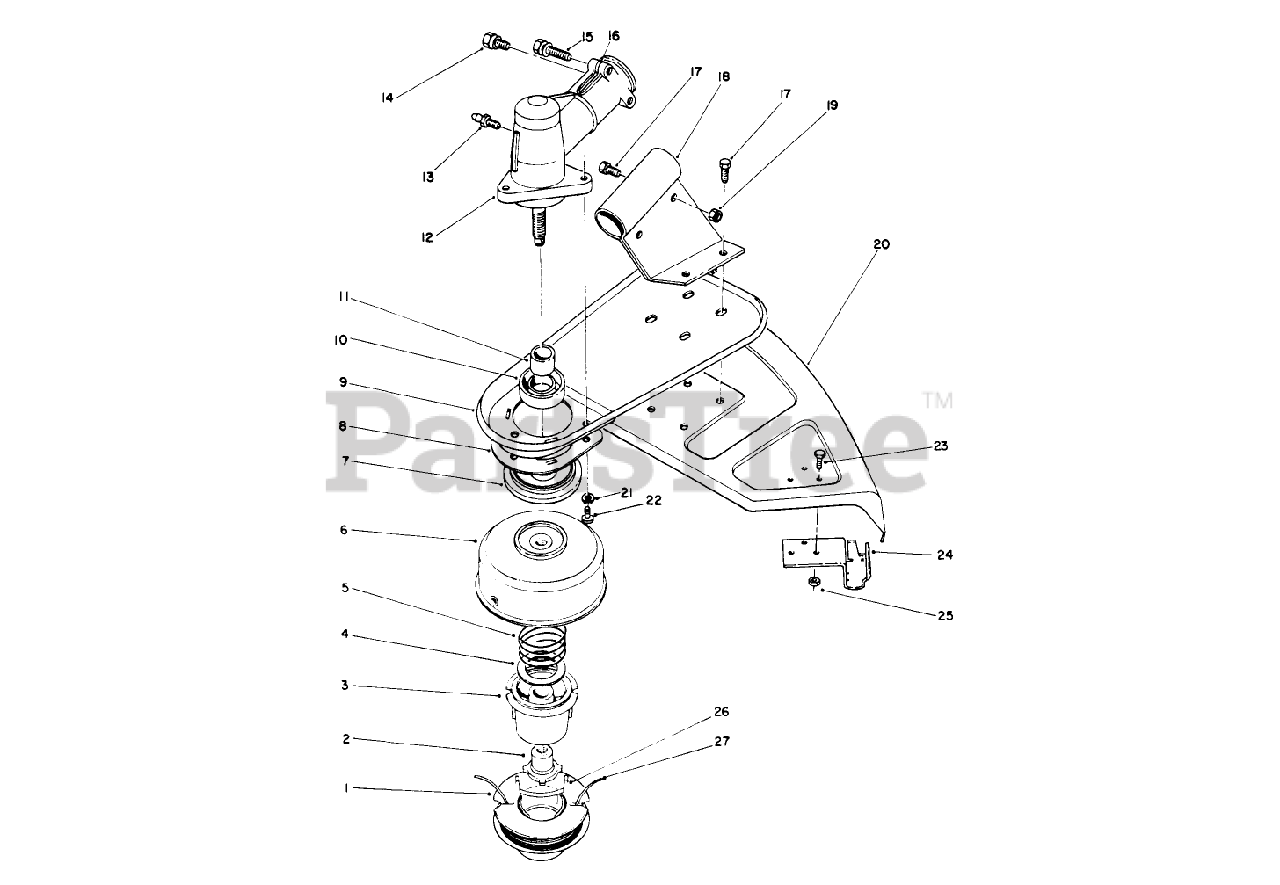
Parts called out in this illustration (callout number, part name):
3	SPOOL CORE
4	WASHER-FLAT
5	SPRING
7	DUST CAP F/W
8	GRASS WRAP GUARD
9	SHIELD SUPPORT *R
10	OIL SEAL
12	GEARBOX
14	HHMS SCREW
17	SCREW-SHH
18	SHIELD BRKT
19	NUT-LOCK, NI
23	SCREW-SHH
24	BRACKET & KNIFE ASM
25	NUT-LOCK, NI
